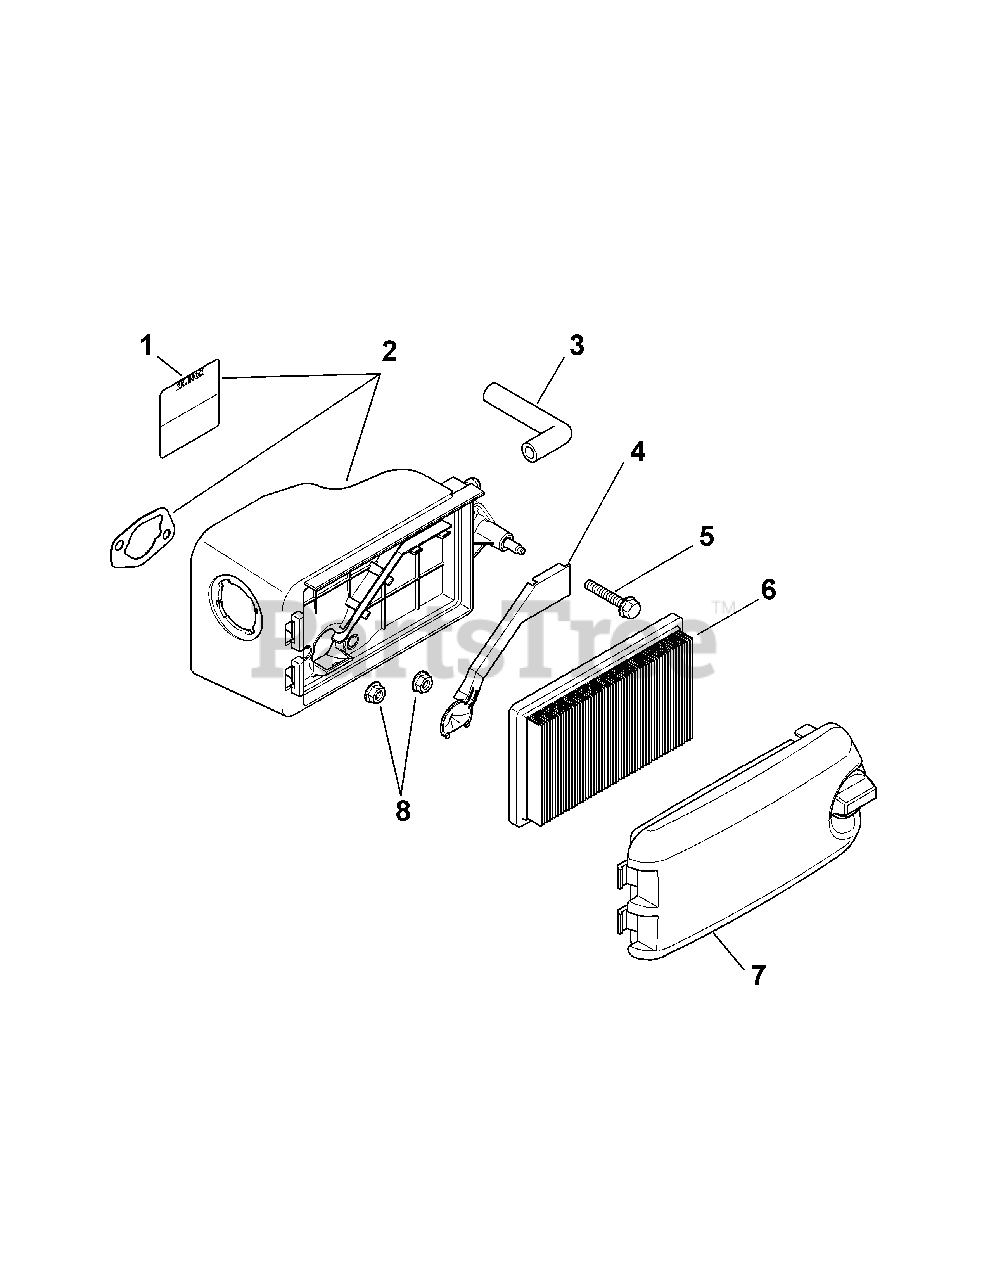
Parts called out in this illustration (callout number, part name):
1	Nameplate, Service
2	Kit, Air Cleaner Base (Primer) (Includes 1, Air Cleaner Base Gasket)
3	Hose, Breather
4	Cover, A/C Base (Breather Gas)
5	Screw, Hex Flange (M6)
6	Element, Air Cleaner
7	Kit, Air Cleaner Cover
8	Nut, Flg M6X1.0
